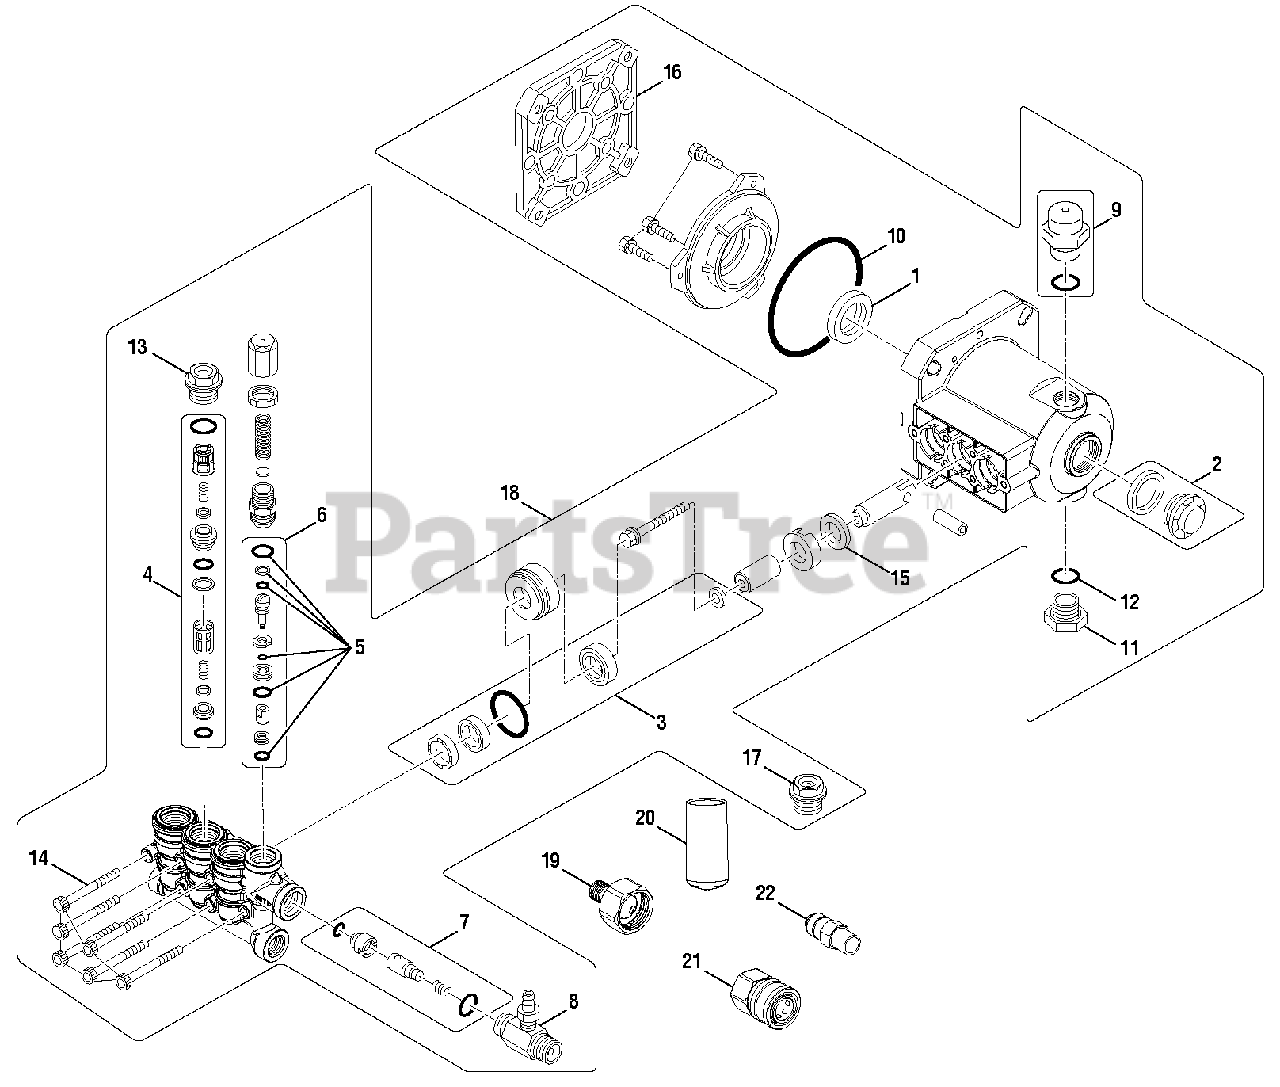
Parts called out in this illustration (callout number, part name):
4	Valve Assembly
5	O-Ring Kit
6	Unloader Kit
7	Check Valve Kit
8	Fixed Injector
9	Oil Fill Cap w/O-Ring
11	Drain Plug
16	Pump Flange
17	Idle Down Plug
18	Pump Assembly (4GXT27)
19	Garden Hose Coupler w/Filter
20	Unloader Cap
21	Quick Connect (3/8 in.)
22	Thermal Release Valve
